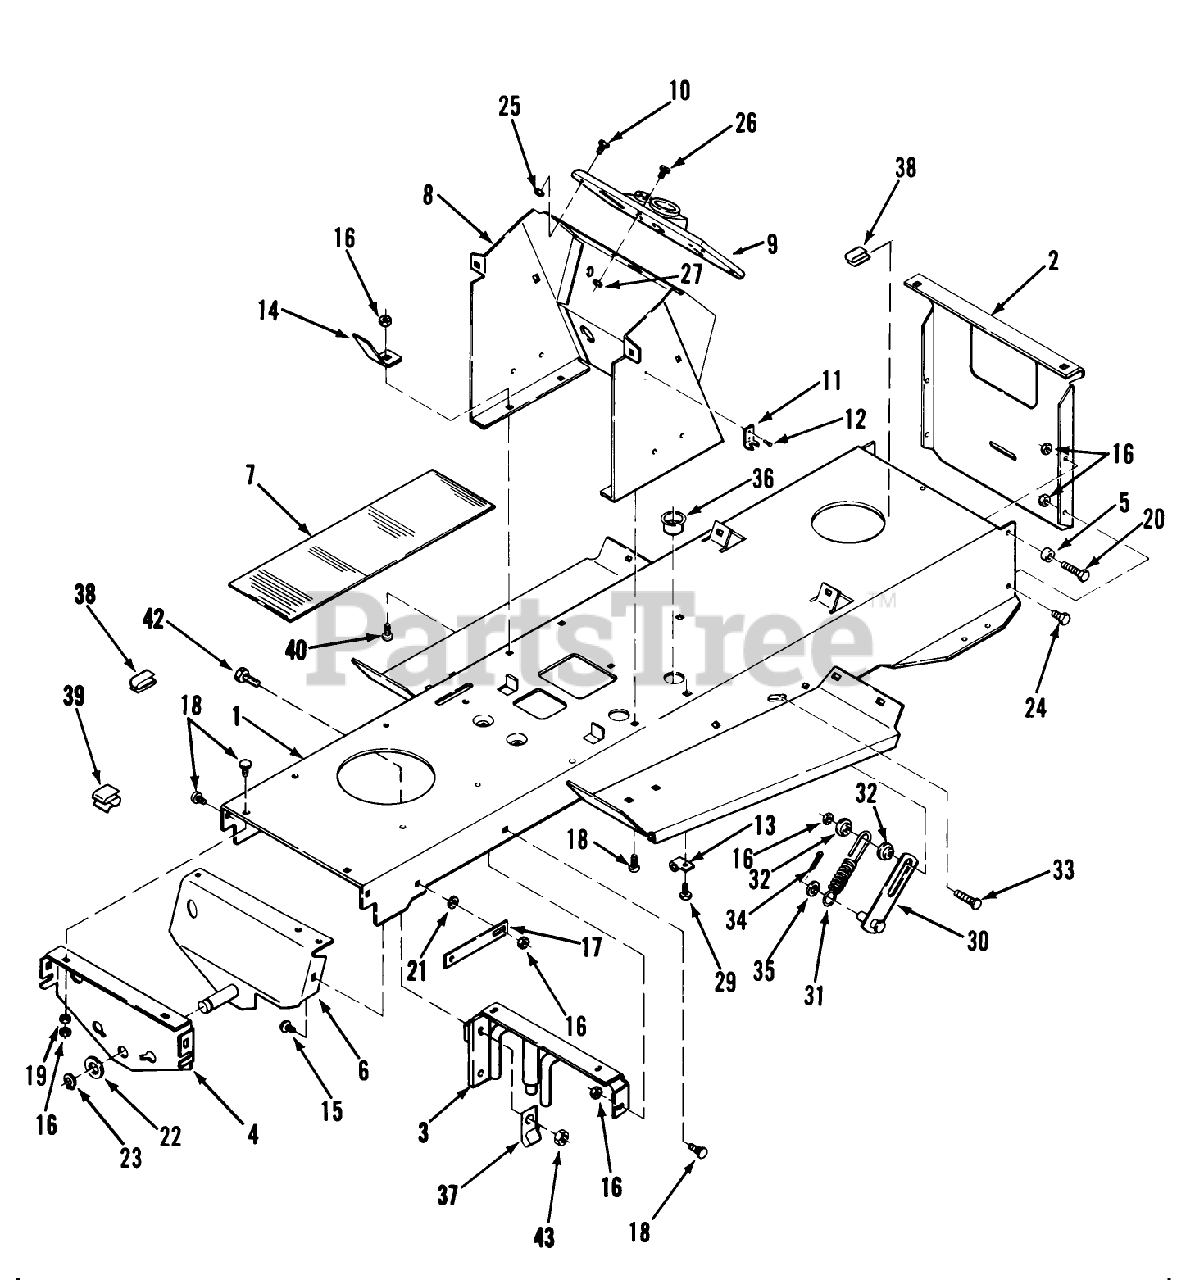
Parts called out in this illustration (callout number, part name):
2	PLATE DRAWBAR
4	PLATE SUPT - AXLE *R
5	BEARING CAM ROLLER
7	PAD-FOOTREST
8	HOODSTAND ASSY *B
13	J-CLIP
17	STRAP *R
19	WASHER 5/16 SAE
22	WASHER
22	WASHER-SHIM
31	SPRING
35	WASHER-FLAT
36	BUSHING-NYLON 1.093
37	CLIP
39	CLIP-CABLE
